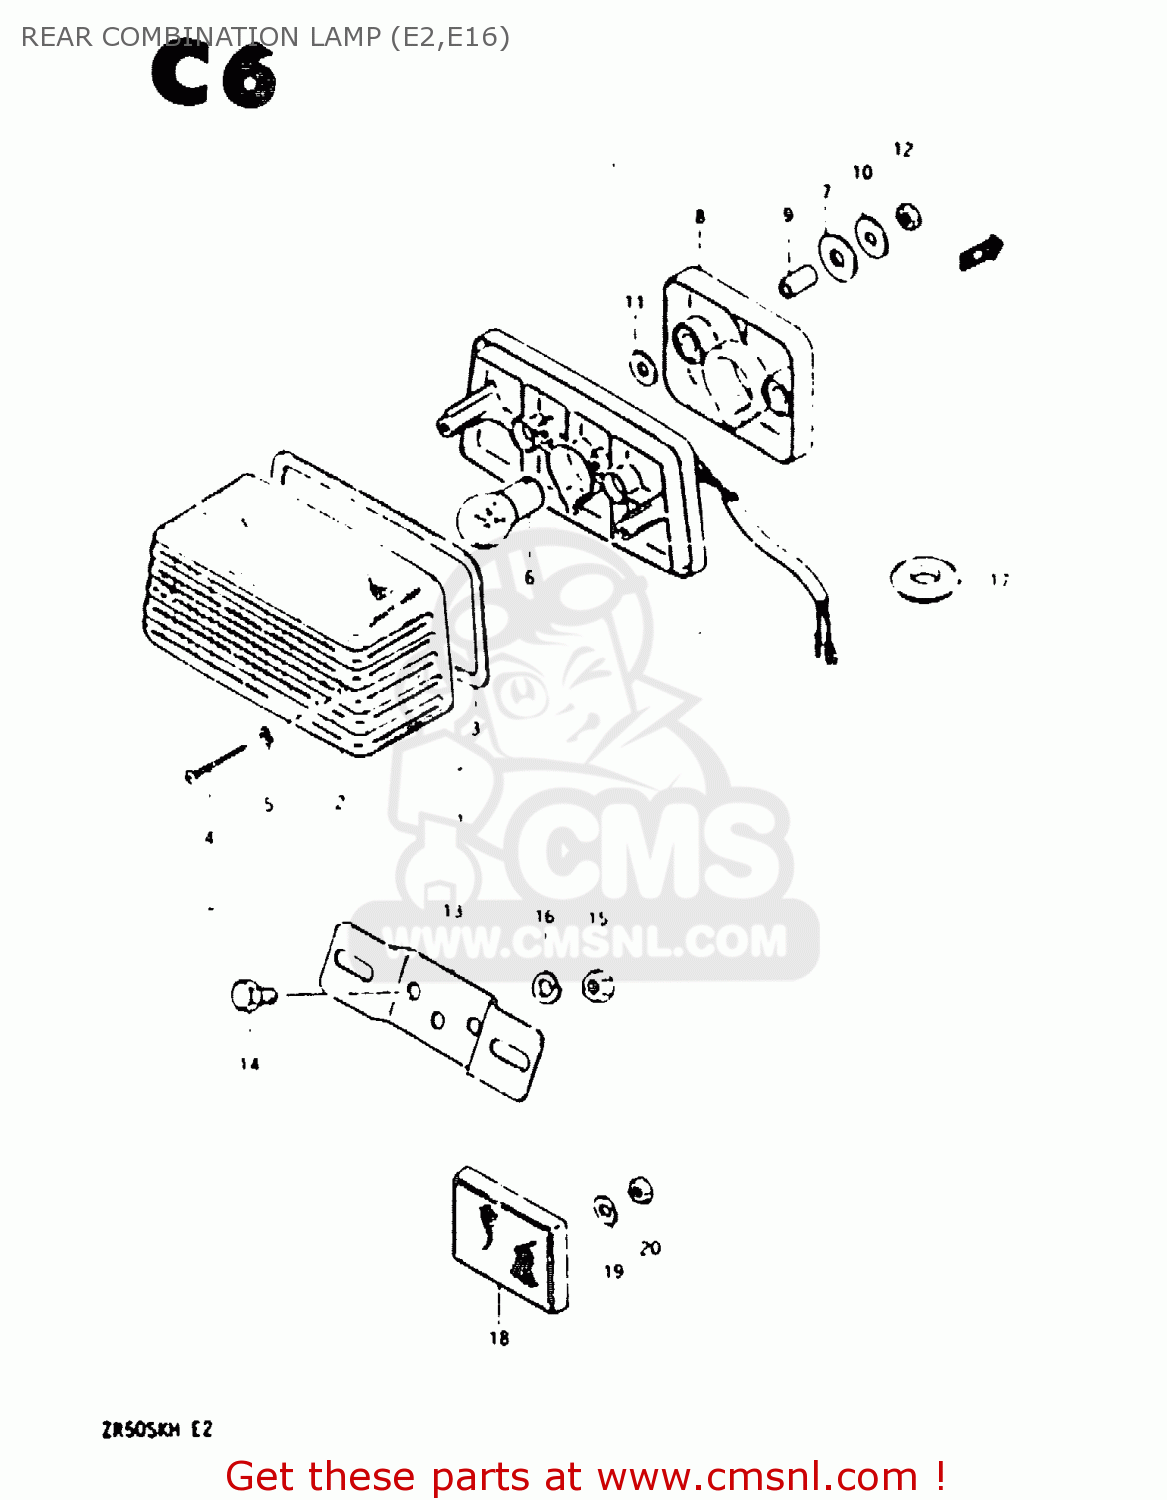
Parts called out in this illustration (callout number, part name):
1	LAMP ASSY, REAR COMBINATION
2	LENS
3	GASKET (NAS)
4	SCREW
5	GASKET (NAS)
6	BULB (6V,21/5W)
7	CUSHION,RR COMBINATION LAMP
8	CUSHION
9	SPACER
10	WASHER (5.5X20X1.2)
11	WASHER(5.2X16X1)
12	NUT
13	BRACKET, LICENSE PLATE
14	BOLT
15	NUT
16	WASHER,LOCK
17	GROMMET
18	REFLEX REFLECTOR,RR
19	WASHER(5.2X16X1)
20	NUT
